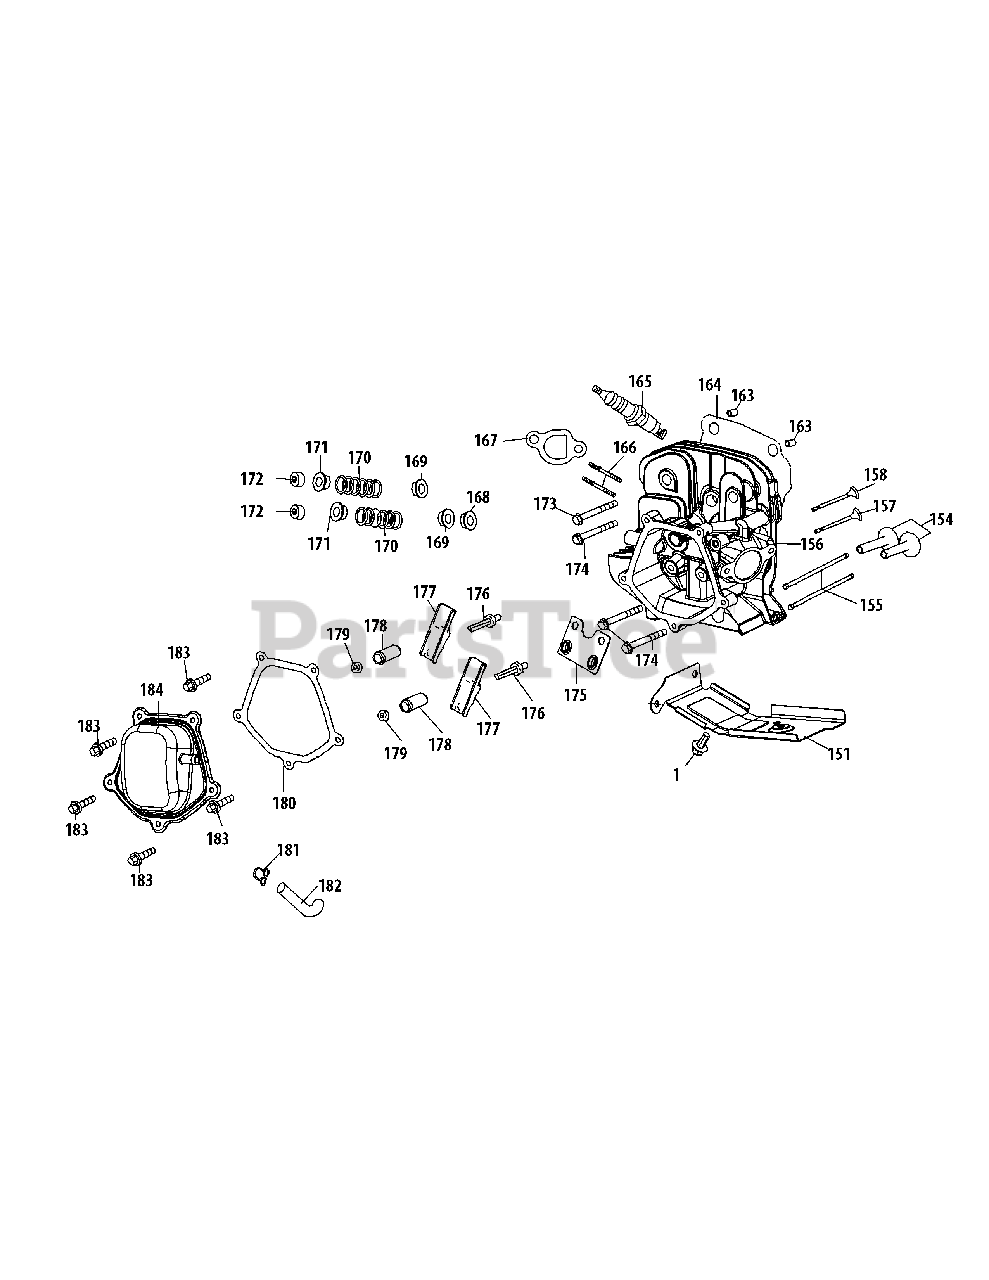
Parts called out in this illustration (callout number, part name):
1	BOLT M6×12
154	TAPPET
155	PUSH ROD
156	CYLINDER HEAD
157	INTAKE VALVE
158	EXHAUST VALVE
159	GOVERNOR ARM SHAFT
160	GOVERNOR SEAL
161	WASHER 8×20×0.8
162	COTTER PIN
163	DOWEL PIN 12×20
164	GASKET, CYLINDER HEAD
165	SPARK PLUG/F6RTC
166	STUD M8×48.5
167	EXHAUST PIPE GASKET
168	VALVE SEAL (INTAKE)
169	VALVE SPRING RETAINER(INTAKE)
170	VALVE SPRING
171	VALVE SPRING RETAINER (EXHAUST)
172	EXHAUST LASH CAP
173	BOLT M10×1.25×65
174	BOLT M10×1.25×87
175	PUSH ROD GUIDE
176	BOLT,PIVOT
177	ROCKER ARM
178	ADJUSTING NUT ,VALVE
179	NUT, PIVOT LOCKING
180	VALVE COVER GASKET
181	BREATHER HOSE CLAMP
182	BREATHER HOSE
183	VALVE COVER BOLT
184	VALVE COVER
